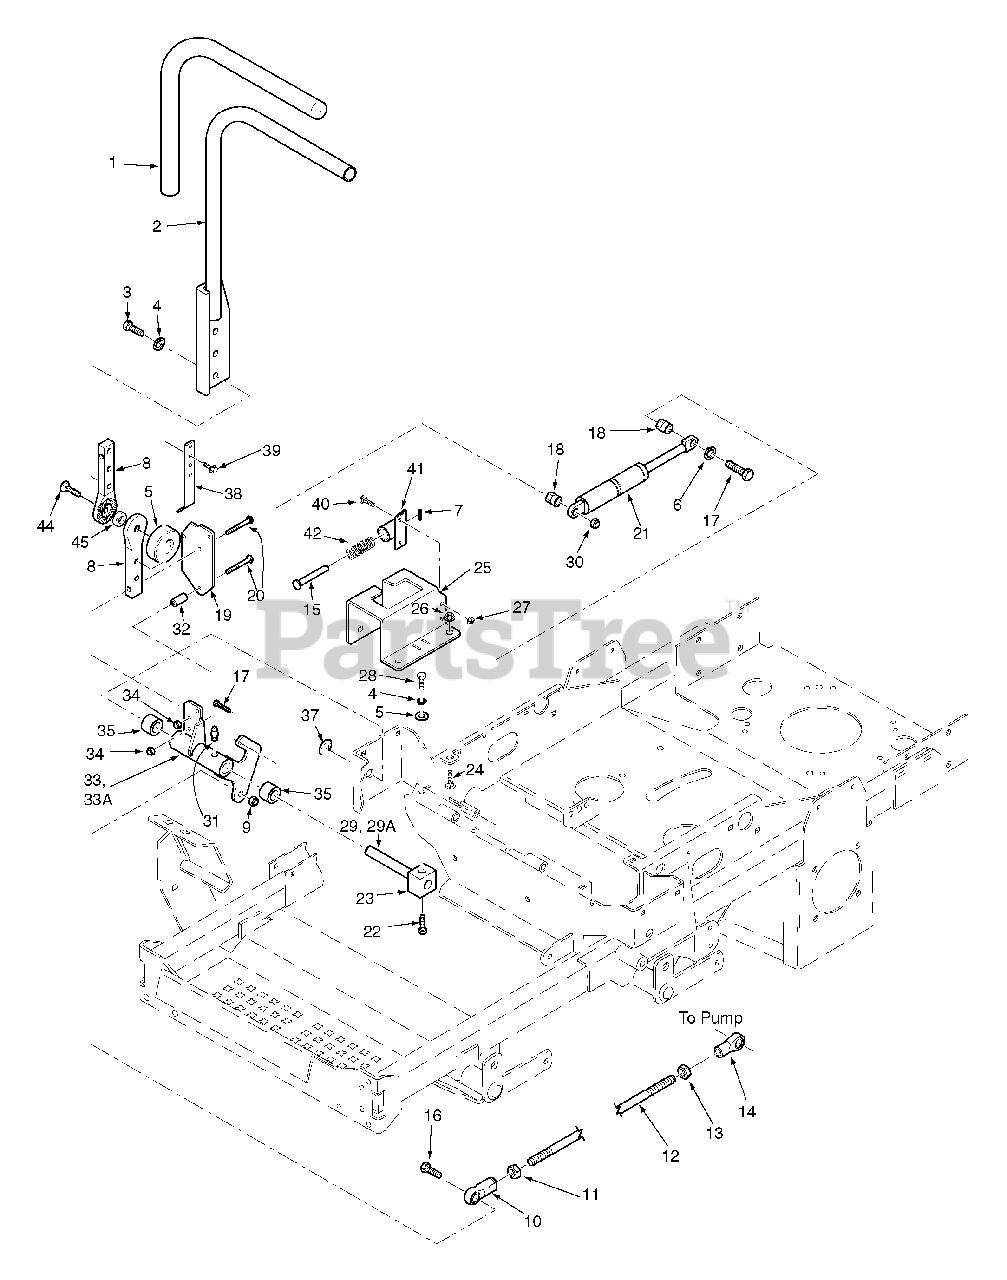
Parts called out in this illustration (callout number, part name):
1	Grip, Control Lever
2	Handle Bar, L.H.
3	Bolt, Hex Head 5/16-18 x 1"
4	Lock Washer, 5/16"
6	Flatwasher, 5/16-.375 x .875 x .083
7	Roll Pin, Spring 5/32 x 3/4"
8	Pivot, Control Lever
9	Nut, Elastic Stop 3/8-16
10	Rod End, 3/8-24 RH Female
11	Nut, 3/8-24 RH Thread
12	Rod, Pump Control Linkage
13	Nut, 3/8-24 UNF-2B LH Thread
14	Rod End, 3/8-24 LH Thread
15	Pin Retainer
16	Bolt, Hex Head 3/8-16 x 1-1/2"
17	Bolt, Hex Head 5/16-18 x 1-3/4"
18	Spacer, Pump Dampener
19	Plate, Control Lever
20	Bolt, Hex Head 5/16-18 x 2"
21	Gas Damper
22	Bolt, Hex Head 3/8-16 x 1"
23	Block, Clamping
24	Bolt, Carriage, 5/16-18 x 3/4"
25	Control Plate - LH
26	Nut, Serr., Flange, 5/16-18
27	Nut, Elastic Stop 1/4-20
28	Bolt, Hex Head 3/8-16 x 3/4"
29	Shaft, Steering Control
30	Nut, Elastic Stop 5/16-18
31	Grease Fitting, 1/4-28 Self Tap
32	Spacer, Control
33	Control Lever Assy RH
34	Nut, Elastic Stop 5/16-18
35	Bushing
36	Flatwasher, 1-1/4 x 49/64 x 16 Ga.
37	Retaining Ring, 3/4" Ext.
38	Bracket, Switch Actuator
39	Bolt, Hex Serr. Flange 5/16-18 x 3/4"
40	Bolt, Carr. 1/4-20 x 3/4"
41	Bracket, Control Return
42	Spring
43	Pin Retainer
44	Bolt, Carriage 5/16-18 x 1-1/2"
45	Rubber Spacer
